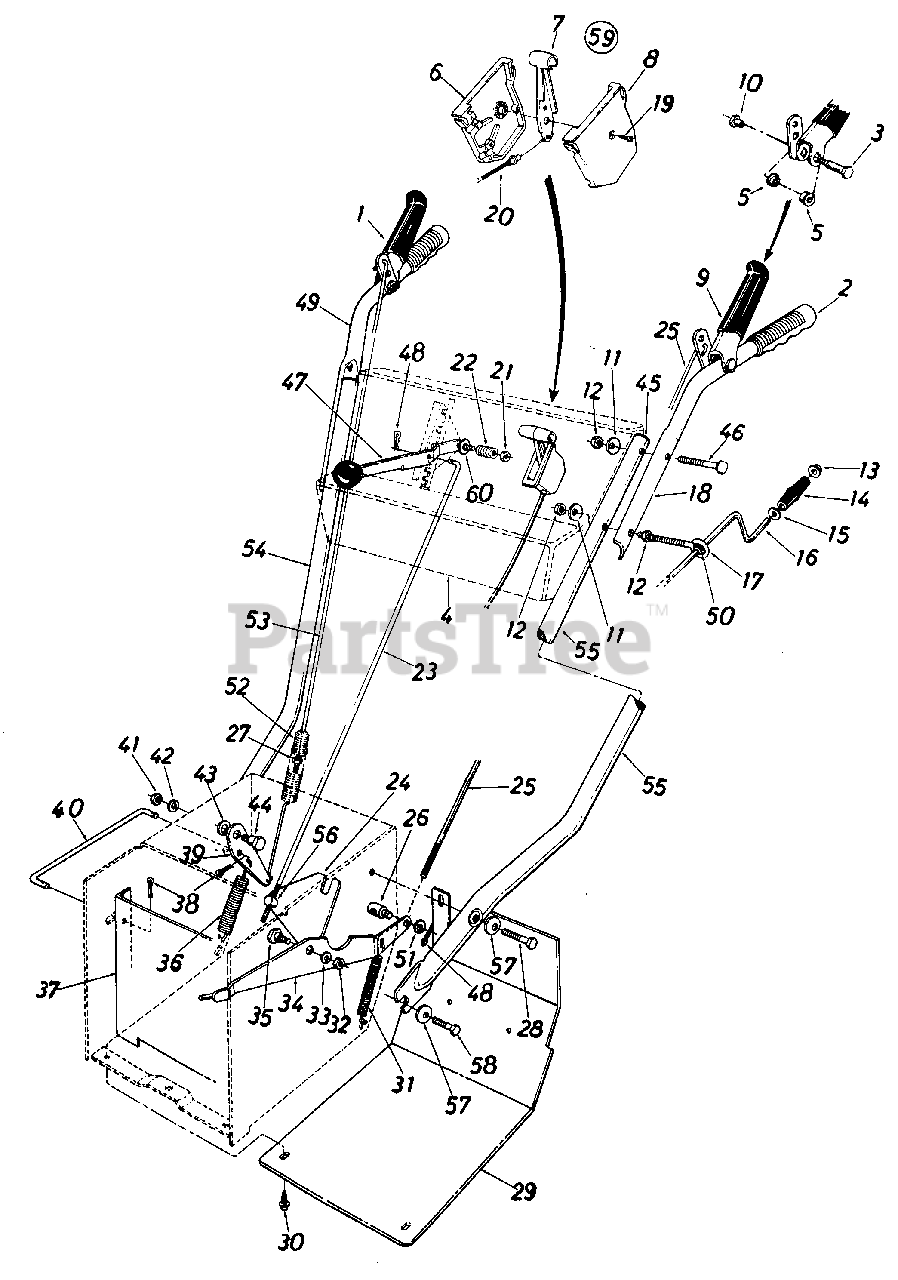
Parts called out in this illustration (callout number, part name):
1	Clutch Grip Ass'y.-R.H.
2	Grip
3	Shoulder Bolt .374 Dia. x 1.53" Lg.
4	Handle Panel Ass'y.
5	Hex Flange Plastic Bearing .380" I.D.
9	Clutch Grip Ass'y.-L.H.
10	Shoulder Nut 1/4-20 Thd.
11	Bell-Wash. .34" I.D. x .88" O.D.
12	Hex Nut 5/16-18 Thd.*
13	Push Nut 3/8" Rod
14	Knob 3/8" Rod
15	Fl-Wash. .40" I.D. x .62" O.D.
16	Chute Crank Ass'y.
17	Eye Bolt 5/16-18 x 5.0" Lg.
18	Upper Handle-L.H.
20	Throttle Control Wire
21	Hex Ins. Jam L-Nut 3/8-24 Thd.
22	Compression Spring .50" O.D. x .88" Lg.
23	Shifting Rod 5/16" x 32.50" Lg.
24	Shifting Linkage Bracket
25	Lockout Rod .214" Dia. x 36.0" Lg.
26	Adjustment Ferrule 1/4-20
27	Hex Ins. L-Nut 1/4-20 Thd.
28	Hex Bolt 3/8-16 x 2.00" Lg.*
29	Frame Cover
30	Hex Wash. Self-Tap Scr. 1/4-20 x .50" Lg.
31	Extension Spring .38" O.D. x 3.25 " Lg.
32	Hex Jam Nut 3/8-16 Thd.*
33	L-Wash. 3/8" I.D.*
34	Auger Clutch Bracket Ass'y.
35	Shld. Bolt .625" Dia. x .170
36	Extension Spring .75" O.D. x 4.31" Lg.
37	Drive Pulley Support Brkt. Ass'y.
38	Cotter Pin 3/32" Dia. x .75" Lg. *
39	Drive Clutch Bracket
40	Drive Clutch Rod
41	Hex Jam Nut 3/8-16 Thd.*
42	L-Wash. 3/8" I.D.*
43	Fl-Wash. .34" I.D. x .75" O.D.
44	Shld. Bolt .625" Dia. x .170
45	Plastic Plug
46	Carriage Bolt 5/16-18 x 2.0" Lg.
47	Shift Handle Ass'y.
48	Int. Cotter Pin 5/16" Dia.
49	Upper Handle-R.H.
50	Grommet
51	Fl-Wash. .28" I.D. x .62" O.D.
52	Extension Spring .75" O.D. x 5.00" Lg.
53	Lockout Rod .214" Dia. x 32" Lg.
54	Lower Handle-R.H.
55	Lower Handle-L.H.
56	Adjustment Ferrule
57	Bell-Wash. .40" I.D. x .88" O.D.
58	Hex Wash. Self-Tap Scr. 3/8-16 x .75" Lg.
59	Throttle Control Box Ass'y.
60	Bell-Wash. .40" I.D. x .88" O.D.
